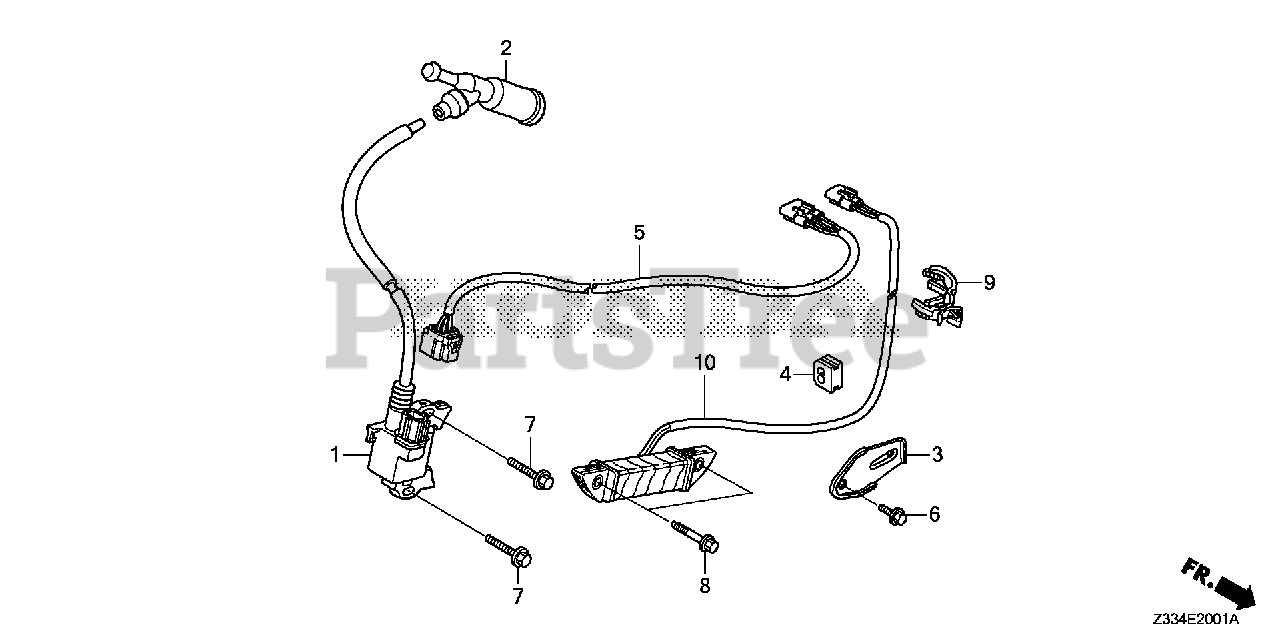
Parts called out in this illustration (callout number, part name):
1	COIL ASSY., IGNITION
2	CAP ASSY., NOISE SUPPRESSOR (NGK Y-EZD)
3	CLAMP, WIRE
4	GROMMET, WIRE
5	WIRE HARNESS ASSY., ENGINE
6	BOLT, FLANGE (6X12) (CT200)
7	BOLT, FLANGE (6X28) (CT200) Use up to Engine SN 1530314.
8	BOLT, FLANGE (6X25) Use up to Engine SN 2056819.
9	CLIP, WIRE HARNESS
10	COIL ASSY., POWER
